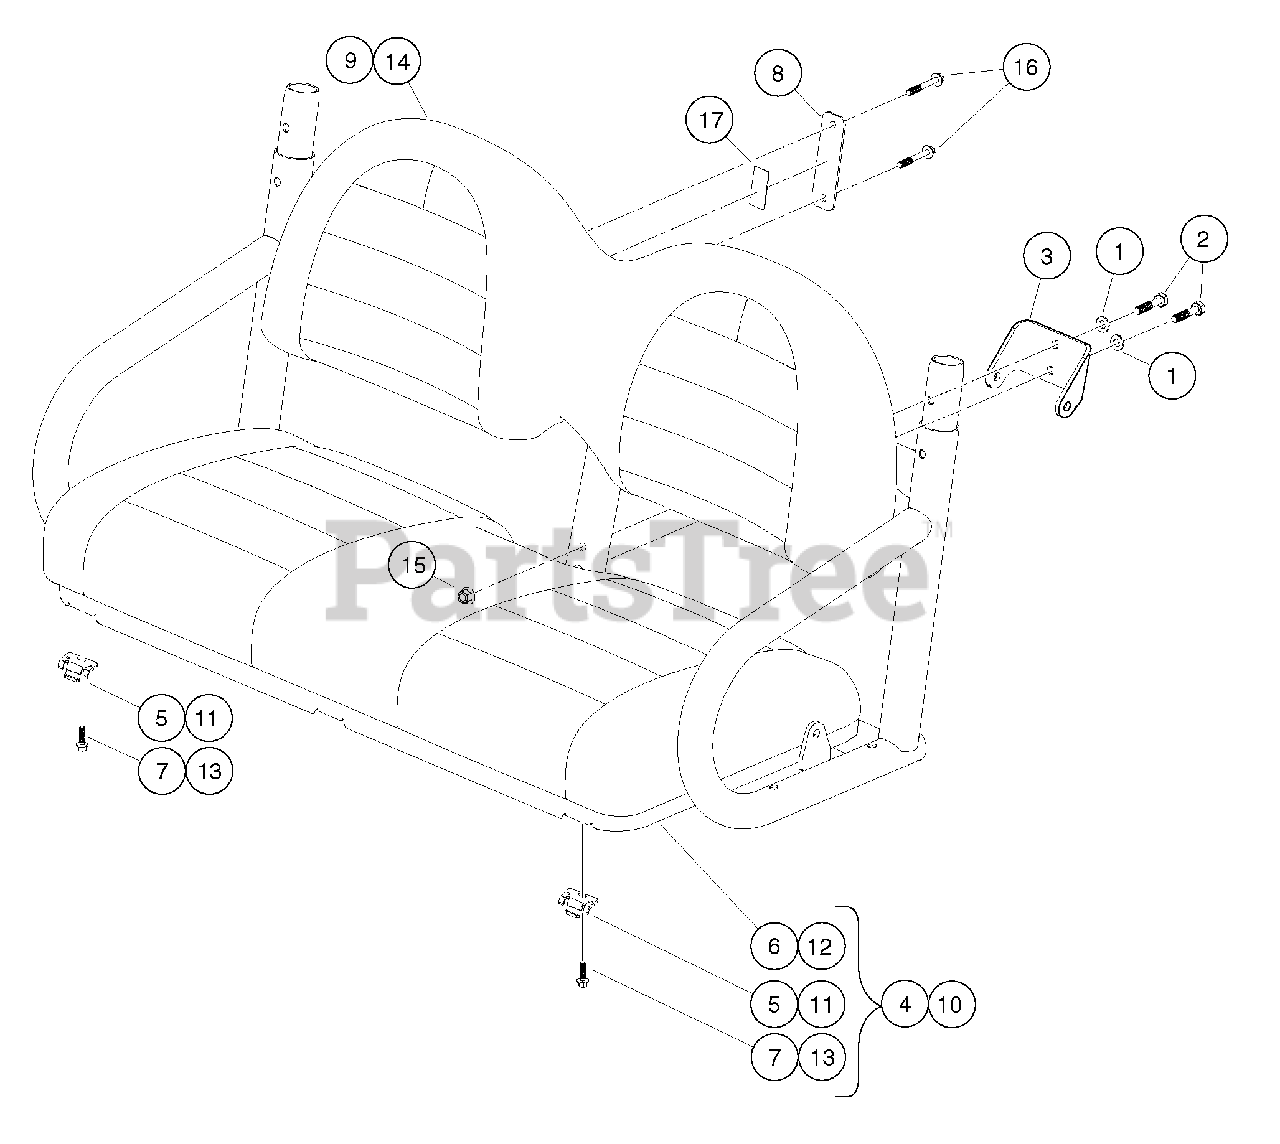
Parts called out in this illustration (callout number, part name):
1	Washer, Hard, M10, Zn-Ni/Blk
2	Bolt, M10 X 45, Zn-Ni (Black)
3	Bracket, Seat Belt, Bench
4	Asm, Seat Bottom, Bench, Gray
5	Hinge Plate
6	Asm, Seat Bottom, Bench
7	Bolt Flg Blk, M8 X 25, Loctite
8	Bracket, Seat Back, AWD
9	Seat Back, Bench, Gray
10	Asm, Seat Bottom, Bench, Black
11	Hinge Plate
12	Seat Bottom, Bench, Black
13	Bolt Flg Blk, M8 X 25, Loctite
14	Seat Back, Bench, Black
15	Nut, Flanged, M10 x 1.5, Black
16	Bolt Flg Blk, M8 X 55, Loctite
17	Tape, Double-Sided, VHB, 1"x 2"
